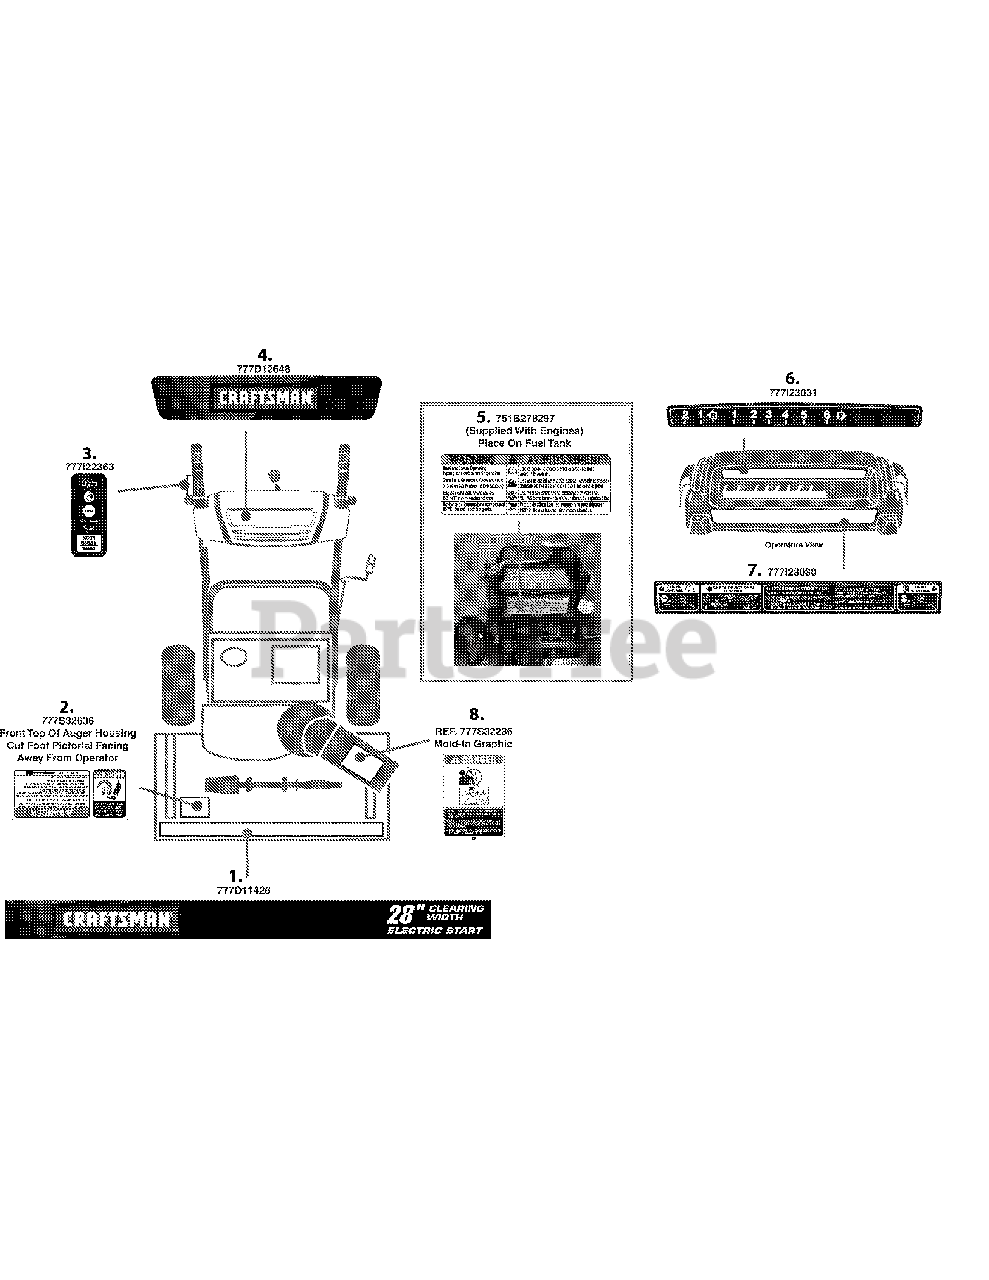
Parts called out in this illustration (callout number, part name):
1	LABEL-SNOW HOUSING CRAFTSMAN 9/28"
2	LABEL-SNOW HOUSING
4	LABEL:SNW:EPNL PLSTC CVR:CRAFTSM
5	LABEL:ENG:B&S 2LANG WARNING SNOW
6	LABEL:SNW:E W.PLST CVR:SPD SLCTR
7	LABEL:SNW:E W.PLST CVR:ST INST
8	LABEL:SNOW CHUTE
